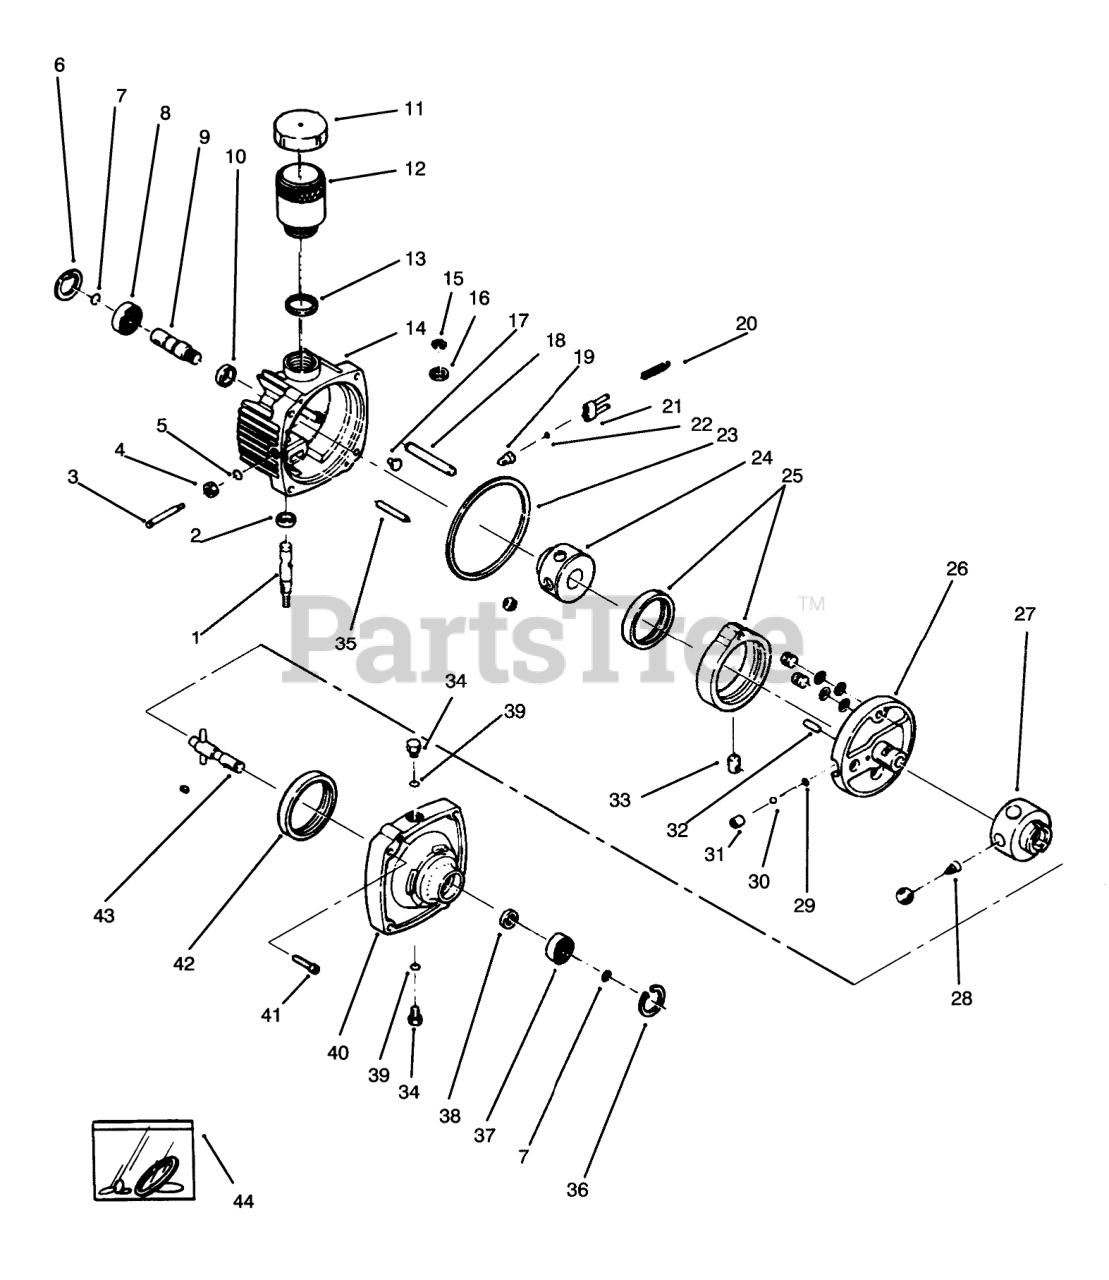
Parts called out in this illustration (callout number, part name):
1	KIT-CONTROL SHAFT
2	SEAL-OIL
3	SHAFT-DUMP VALVE
4	Nut
5	O-RING
6	Retaining Ring
7	SNAP-RING
8	BEARING-BALL (INPUT)
9	SHAFT-INPUT
10	SEAL-OIL
11	RESERVOIR COVER
12	BODY-RESERVOIR
13	SEAL-RING SQUARE CUT
14	Kit-Cover (Incl. Ref. # 1, 2, 10, 15, 16, 18 & 35)
15	RETAINING-RING
16	Washer-Control Shaft
17	Button
18	Dowel (Ref.)
19	SUB-ASS'Y O-RING
20	SPRING-VALVE
21	SUB-ASS'Y BRACKET
22	O-RING
23	SEAL-RING SQUARE CUT
24	SUB-ASS'Y PUMP ROTOR
25	Ring Sub-Assembly-Cam (Incl. Pump Race & Cam Ring)
26	Pintle Assembly-Used in CCW rotation trans. Model #00700-023 (Incl. Ref.#29-32)
27	SUB-ASS'Y MOTOR
28	SPRING-PISTON
29	Ring-Retaining
30	Ball
31	BODY-CHECK VALVE
32	Pin-Coil
33	INSERT-CAM RING
34	Plug Assembly-O-Ring (Incl. Ref. #39)
35	Dowel (Ref.)
37	Bearing-Ball
39	O-Ring
40	Body Assembly (Incl. Ref.# 7, 34, 36-39, 41 & 43)
41	Screw
42	Seal-Oil
43	SUB-ASS'Y OUTPUT
44	Kit-Overhaul Sealing (Incl.
